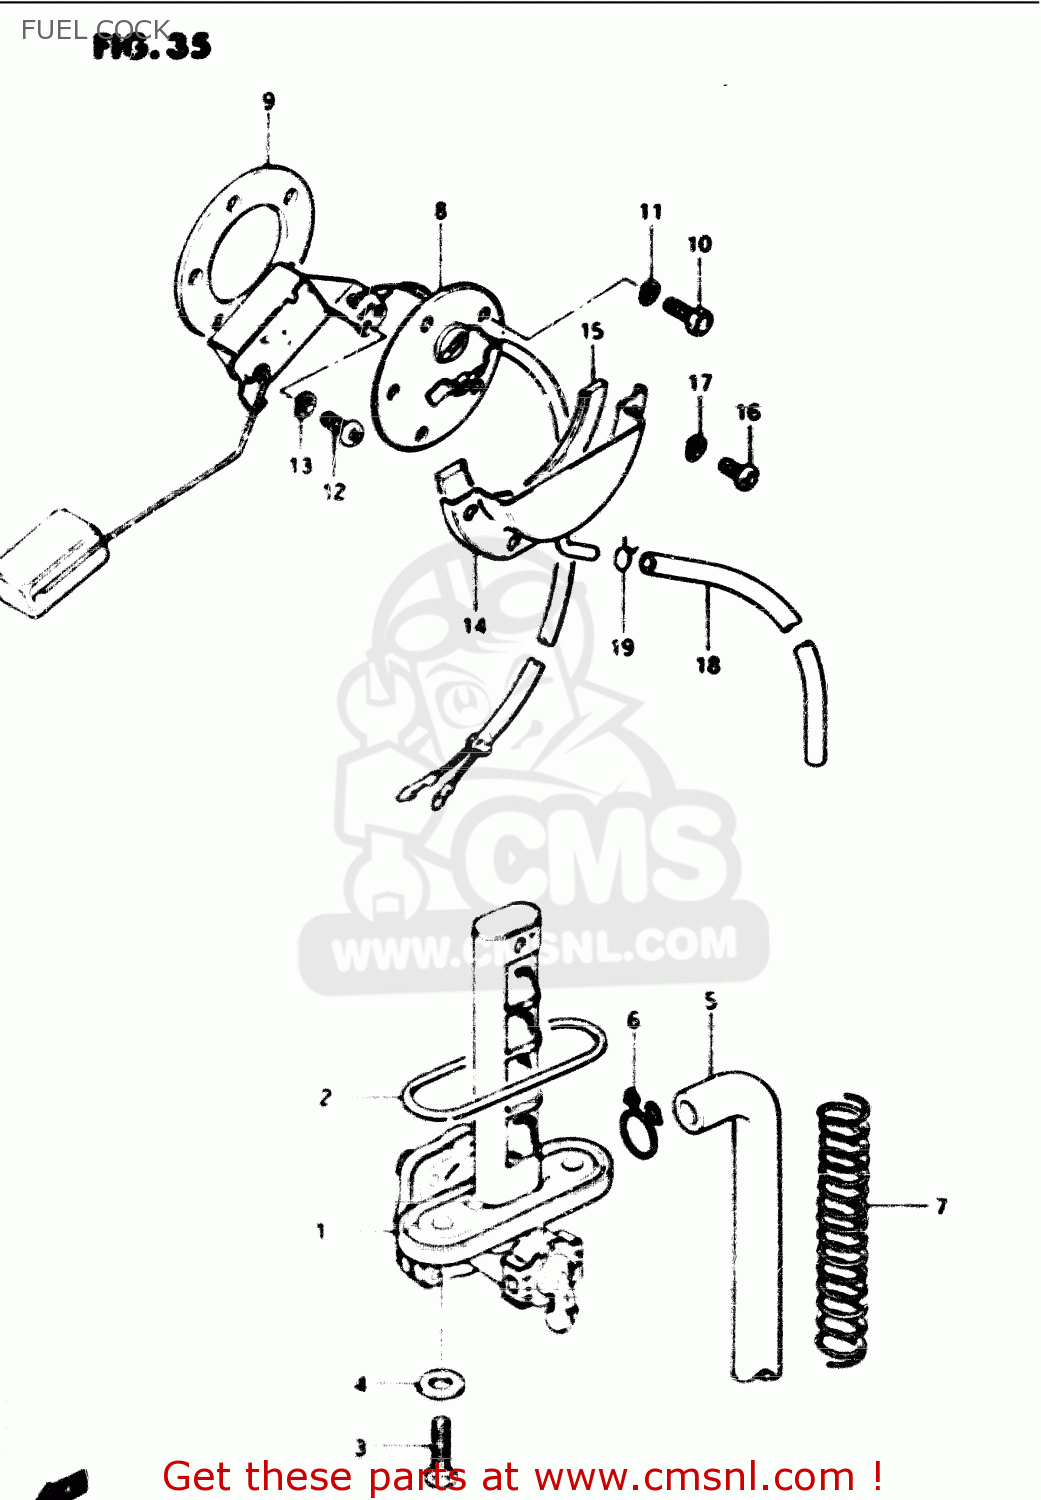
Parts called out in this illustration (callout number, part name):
1	COCK ASSY,FUEL
2	O RING
3	BOLT(6X20)
4	GASKET
5	HOSE
6	CLIP
7	SPRING
8	GAUGE ASSEMBLY,FUEL LEVEL
9	GASKET,FUEL LEVEL GAUGE (NAS)
10	BOLT
11	LOCK WASHER
12	SCREW 5X10
13	LOCK WASHER
14	PLATE,FUEL DRAIN
15	GASKET (NAS)
16	SCREW
17	LOCK WASHER
18	HOSE,FUEL
19	CLIP
